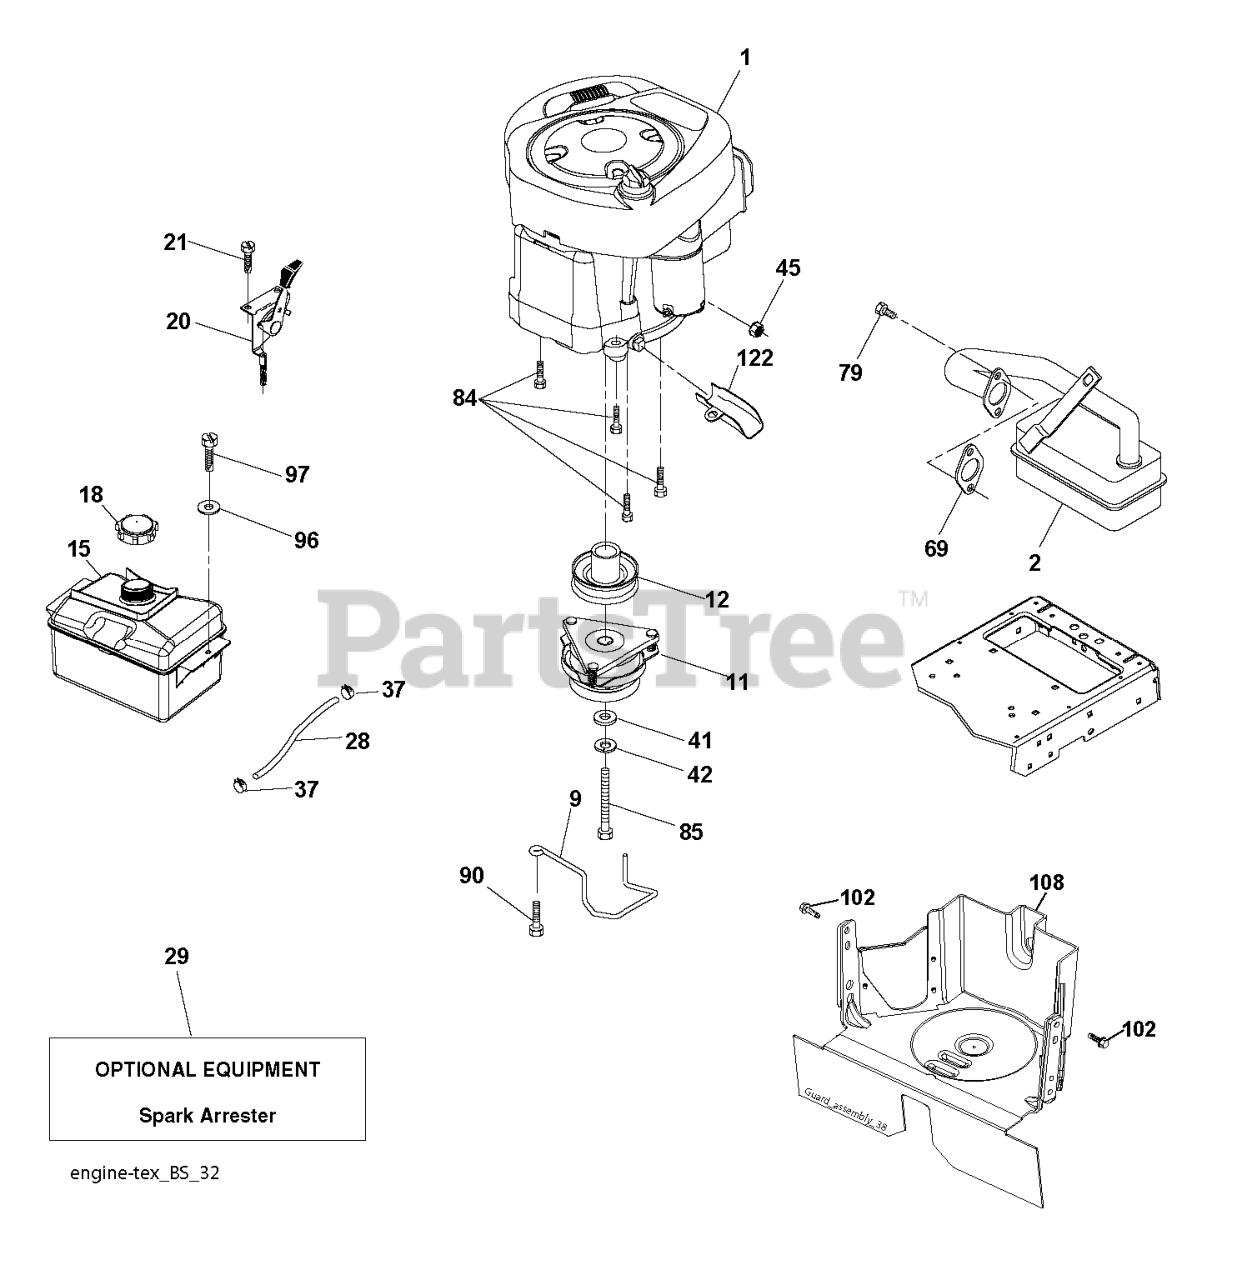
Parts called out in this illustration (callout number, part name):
2	MUFFLER.B&S.MODEL.21.11HP.OHV
9	KEEPER.BELT.ENGINE.3.25 (3 2)
11	RB.CLUTCH.OGURA.4.4.PD
12	PULLEY.ASM.ENG.OGURA.3
15	RP TANK FUEL FRT 1.5 GAL
18	CAP ASM.FUEL.2.25"FR.
20	CONTROL.TH/CK.C.
21	SCREW.#10 X 0.750.BOS
28	LINE.FUEL.20
29	KIT.SPARK ARRESTOR 794945 B&S
37	HOSE CLAMP
42	LOCKWASHER
45	NUT
69	REPL BY 532 27 22-93
79	SCREW.SOCKET HD.5/16-1
84	SCREW.3/8-16
85	BOLT HEX 7/16-20X4-1/4"
90	SCREW 3/8-16X1
97	SCREW HEXWSHR 1/4-20X3/4
102	SCREW
108	COVER PULLEY
122	EXTENSION DRAIN OIL
